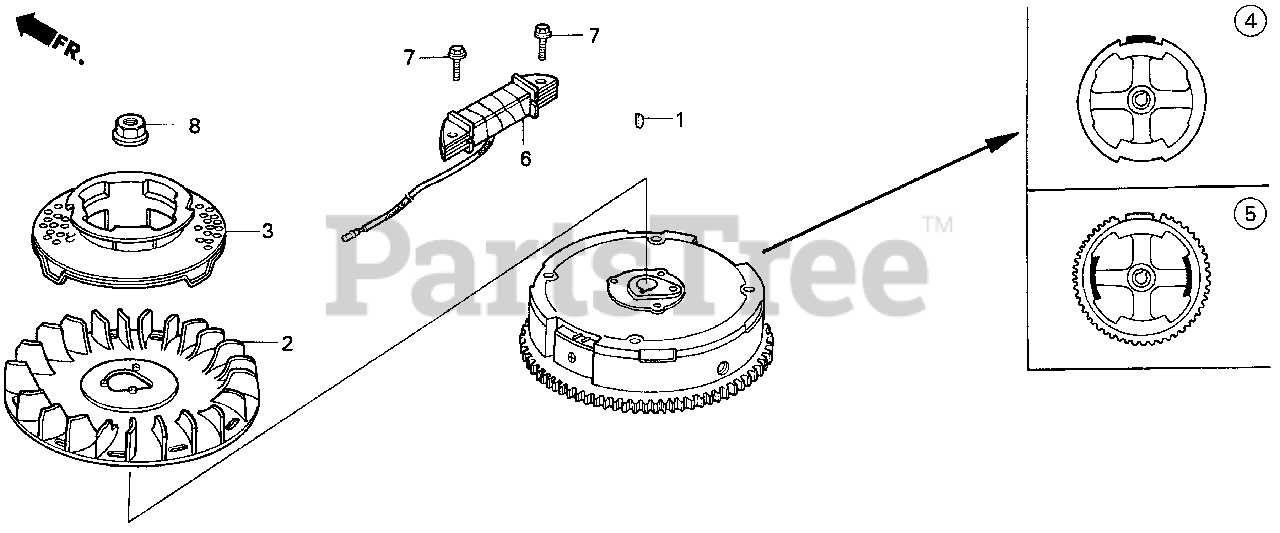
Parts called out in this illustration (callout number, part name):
1	KEY, SPECIAL WOODRUFF (25X18)
2	FAN, COOLING
3	PULLEY, STARTER
5	FLYWHEEL (STARTER MOTOR)
6	COIL ASSY., CHARGE
7	BOLT, FLANGE (6X28)
8	NUT, SPECIAL (14MM)
